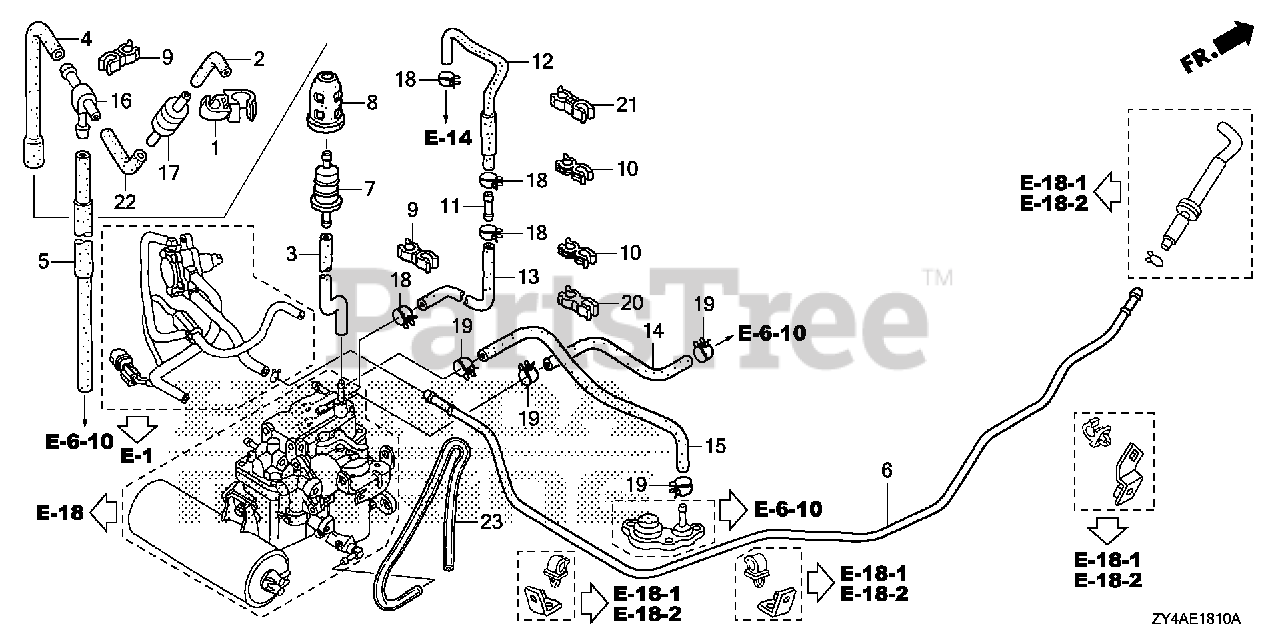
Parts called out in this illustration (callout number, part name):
1	CLAMP, CHECK VALVE
2	TUBE, CHECK VALVE
3	TUBE A, AIR VENT
4	TUBE B, AIR VENT
5	TUBE, AIR VENT
6	PIPE, FUEL
7	FILTER, FUEL PUMP
8	SUSPENSION, STRAINER
9	CLAMP, HOSE
10	CLIP, TUBE
11	JOINT, FUEL RETURN
12	HOSE A, PRESSURE REGULATOR RETURN
13	HOSE B, PRESSURE REGULATOR RETURN
14	TUBE, WATER INLET
15	TUBE, WATER OUTLET
17	VALVE, CHECK
18	CLAMP, TUBE (D10.7)
19	CLAMP, TUBE (D10.5)
20	CLIP, WIRE
21	CLAMP, FUEL TUBE
22	BULK HOSE, FUEL (3.5X3000) (3.5X55)
23	BULK HOSE, VINYL (3.5X6.5X8000) (3.5X6.5X600)
